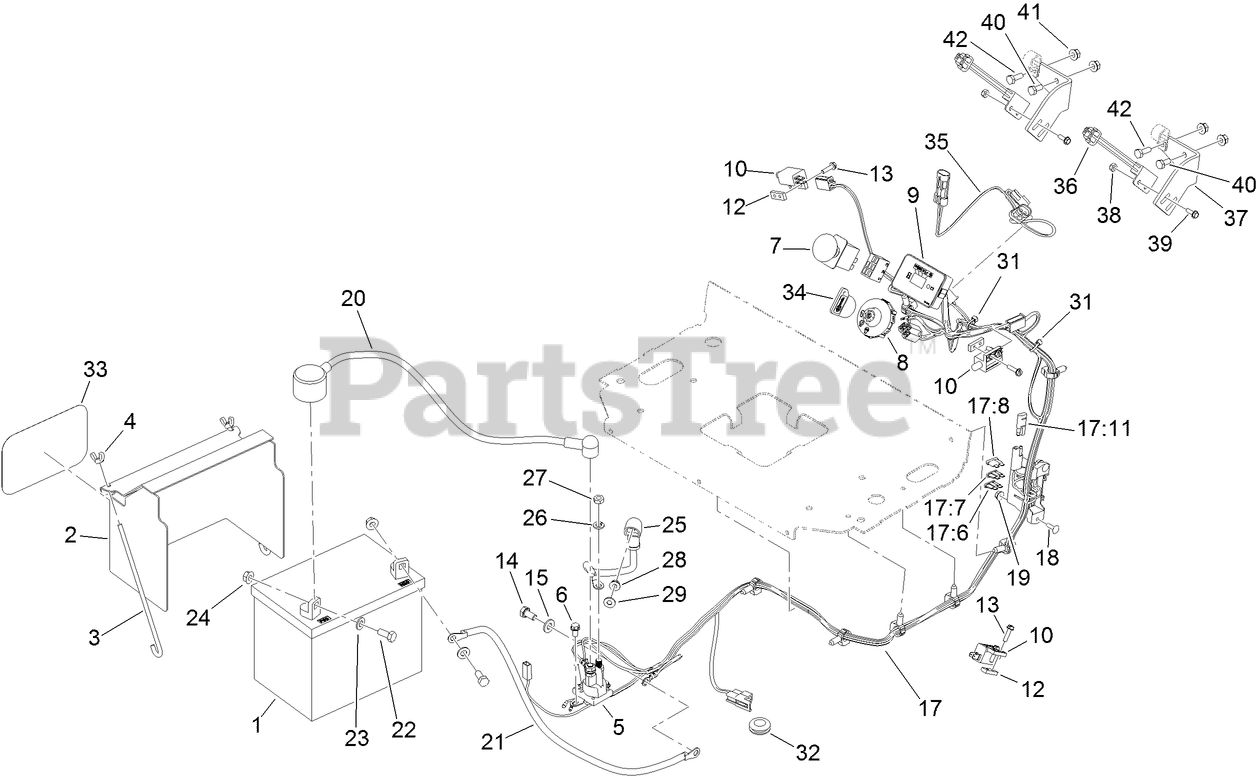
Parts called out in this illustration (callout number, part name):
1	BATTERY
2	COVER-BATTERY
3	BOLT-HOLDDOWN
4	WINGNUT
5	SOLENOID
6	SCREW-HWH
7	SWITCH-PTO, ON-ON-(ON)
8	SWITCH-IGNITION
9	MODULE-METER, HOUR
10	SWITCH-CLOSED, NORMALLY
12	PLATE-TAPPED
13	SCREW-HWH
14	SCREW-HH
15	WASHER-PLAIN
17	HARNESS-WIRING
17:6	FUSE-BLADE, 30 AMP
17:7	FUSE-BLADE, 25 AMP
17:8	FUSE-BLADE, 10 AMP
17:11	CAP-PLUG
18	BOLT-CARR
19	NUT-HF
20	CABLE-BATTERY, POSITIVE
21	CABLE-BATTERY, BLACK
22	SCREW-HH
23	WASHER-PLAIN
24	NUT-HHF, SMOOTH
25	CABLE-BATTERY, RED
26	WASHER-LOCK
27	NUT-JAM
28	NUT-HF
29	WASHER-FLAT
31	TIE-CABLE
32	GROMMET
33	DECAL
34	KEY-IGNITION
35	HARNESS-WIRE, NEUTRAL SWITCH
36	SWITCH-PROXIMITY
37	BRACKET-MOUNT, SWITCH
38	NUT-LOCK, NI
40	SCREW-HH
41	NUT-HHF
42	SCREW-HH
